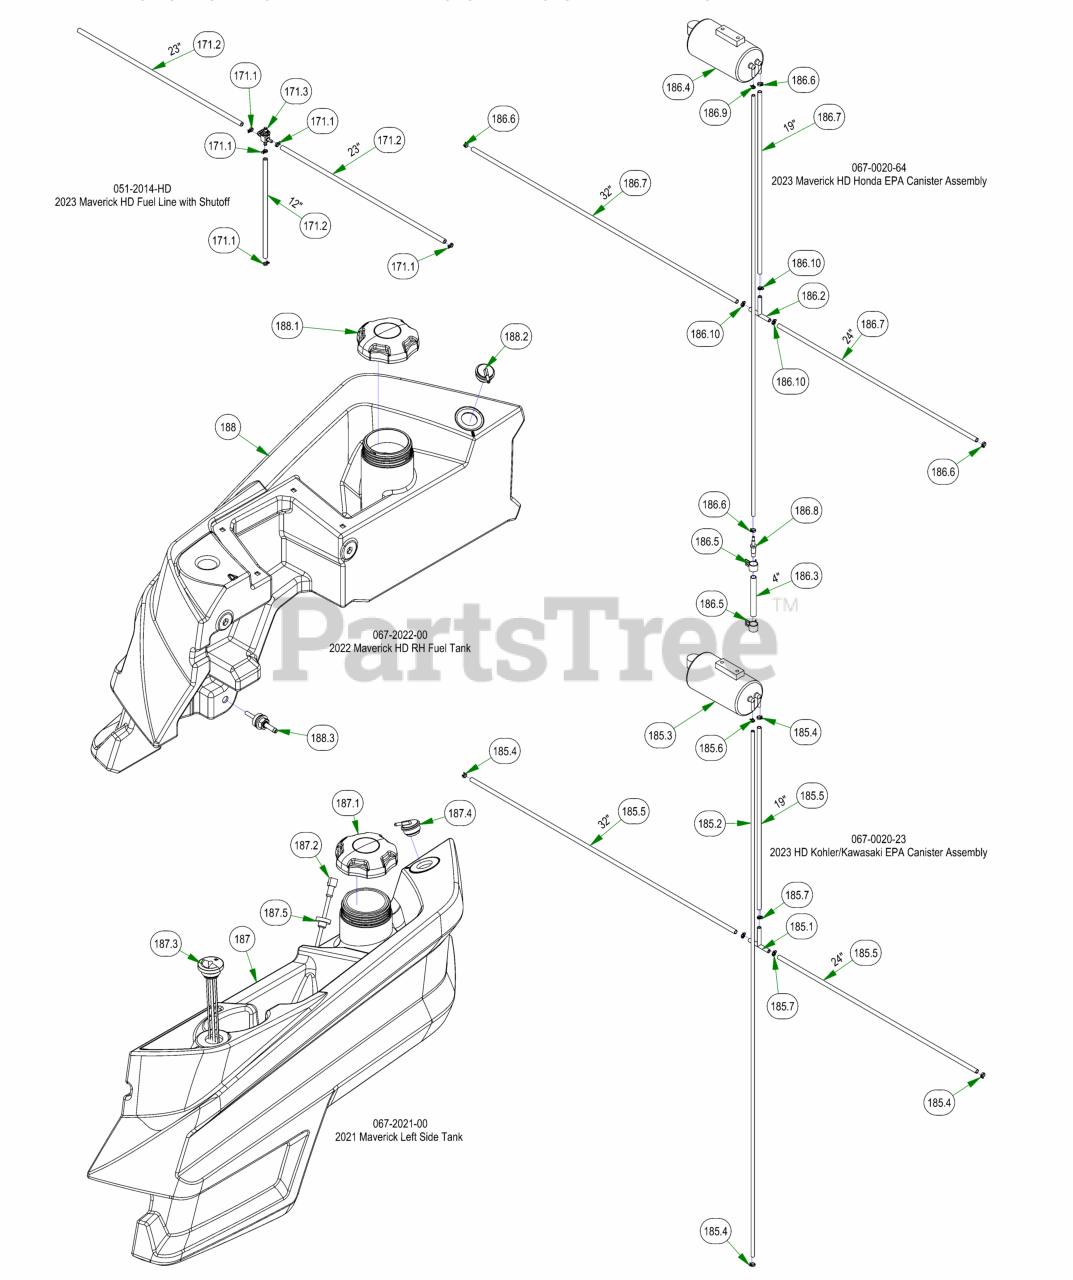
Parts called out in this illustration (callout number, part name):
59	5/16-18 X 1-1/4 CARRIAGE BOLT ZINC
108	2023 4" & 5" Stripping Kit Plate
171	2023 Maverick HD Fuel Line with Shutoff
171.1	1/4 Fuel Hose Clamp
171.2	4" 1/4 Fuel Line
171.3	3 Way Fuel Shut-Off Valve 1/4x1/4x1/4
185	2023 HD Kohler/Kawasaki EPA Canister Assembly
185.1	fuel line T
185.2	3/16" Vinyl Tubing, 55" Long
185.3	Carbon Canister
185.4	3/16 Vinyl Clamp
185.5	1/4" Vinyl Tubing
185.6	8.6mm Hose Clamp
185.7	Roto DW-6.5ST Z3X
186	2023 Maverick HD Honda EPA Canister Assembly
186.1	44" x 3/16" black hose
186.2	fuel line T
186.3	3/8" Black PVC Tubing
186.4	Carbon Canister
186.5	3/8 Hose Clamp - CTB-16-STFS
186.6	3/16 Vinyl Clamp
186.7	1/4" Vinyl Tubing
186.8	3/8-1/4 Nylon Reducer
186.9	8.6mm Hose Clamp
186.10	Roto DW-6.5ST Z3X
187	2021 Maverick Left Side Tank
187.3	Fuel Gauge w/Grommet
187.4	Rollover Valve W/Grommet
187.5	Pick-Up Grommet
188	2022 Maverick HD RH Fuel Tank
188.2	Rollover Valve W/Grommet
188.3	Fuel Pick-up for 067-2022-00
202	2023 ZT Stripping Kit Rubber
